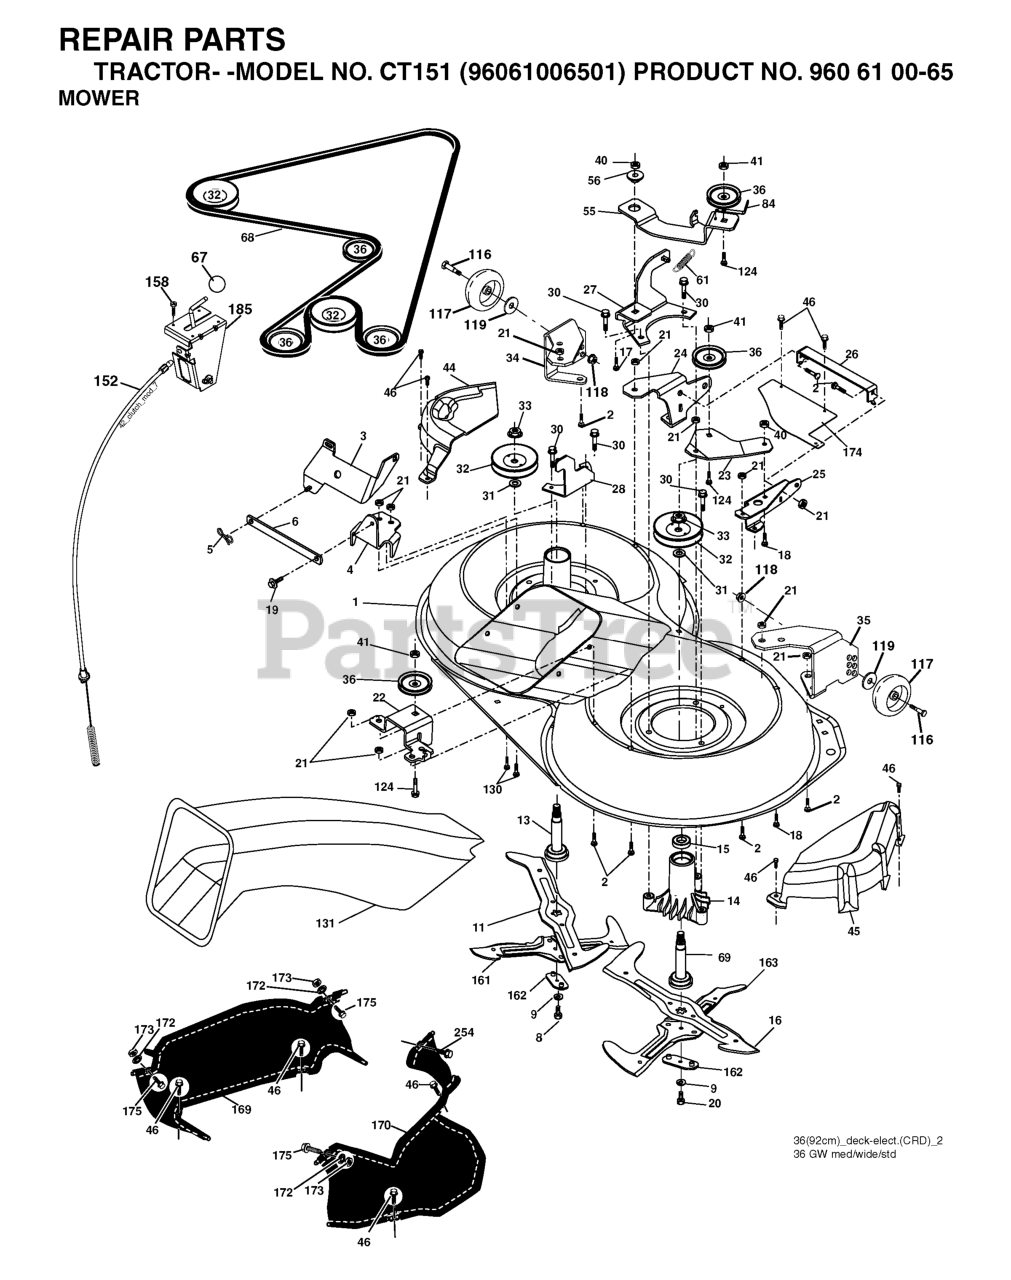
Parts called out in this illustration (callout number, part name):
2	RP BOLT 5/16-18 X3/4 ZN/YEL GR
5	RETAINER-SPRNG RB
6	BAR.SWAY.92.CRD
8	BOLT.3/8-24X1.25 GR8
9	LOCKWASHER
13	SHAFT ASM VENT
14	HOUSING.MANDREL.VENTED (MACHD)
17	BOLT.3/8-14X1.25
18	BOLT
19	BOLT SHD 5/16-18
20	BOLT.3/8-24X1.25GR8. LHTHRD
21	LOCKNUT
26	SUPPORT
30	SCREW, WASHER HEAD
31	WASHER.SPACER.MANDREL
32	PULLEY, MANDREL
33	NUT.FLANGE.LOCK.TOP
36	PULLEY.IDLER.4.25
41	NUT LOCK FLG 3/8-16 UNC
45	COVER.MANDREL.RH.CRD
46	SCREW.1/4-20X5/8
55	ARM.IDLER.92 CRD.2006
56	SPACER.RETAINER.MOWER
61	SPRING.TENSION.BELT
67	KNOB T (3/8 HOLE)
68	BELT.DRIVE.92CM.CRD.2006
69	SHAFT.ASM.W/LWR.BRG.RH.THREAD
84	KEEPER, BELT IDLER
116	SHOULDER BOLT
117	RP WHEEL. GUAGE RALLY
118	LOCKNUT
119	WASHER.5/16.FLAT.STE.STD.
124	BOLT.3/8-16X1.50
130	BOLT.CARR.SQNK.5/16-18UNC.X3/4
131	CHUTE BAGGER
158	SCREW
169	COVER TERMINAL BATTERY
172	PUSH.NUT.ROUND.3/8.DIAM
173	NUT
175	BOLT D
176	WASHER
185	HEAD ASM. CABLE CLUTCH
254	SCREW 3/8-16X1
